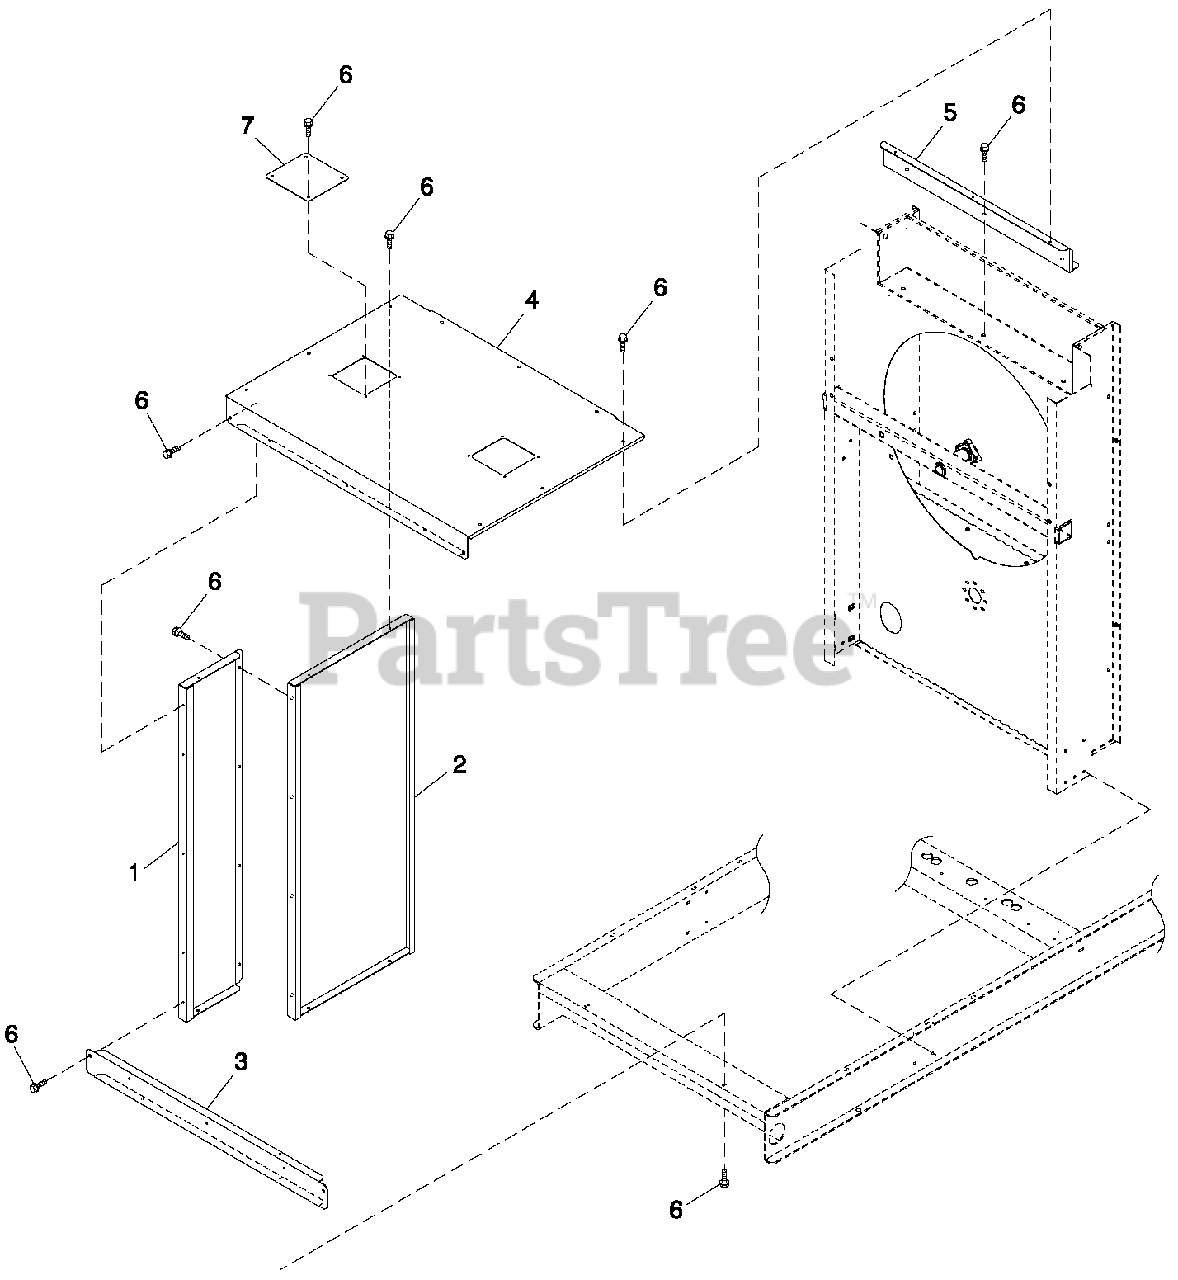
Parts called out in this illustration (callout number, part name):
1	PANEL C5 FRONT SIDES
2	PANEL C5 REAR SIDES
3	PANEL LOWER FRONT
4	PANEL C5 TOP
5	PANEL C5 TOP MOUNT
6	SCREW THF M6-1 X 16 N WA Z/JS
7	ACCESS COVER 160 X 170 GALV
8	SCREW THF M6-1 X 16 N WA Z/JS
